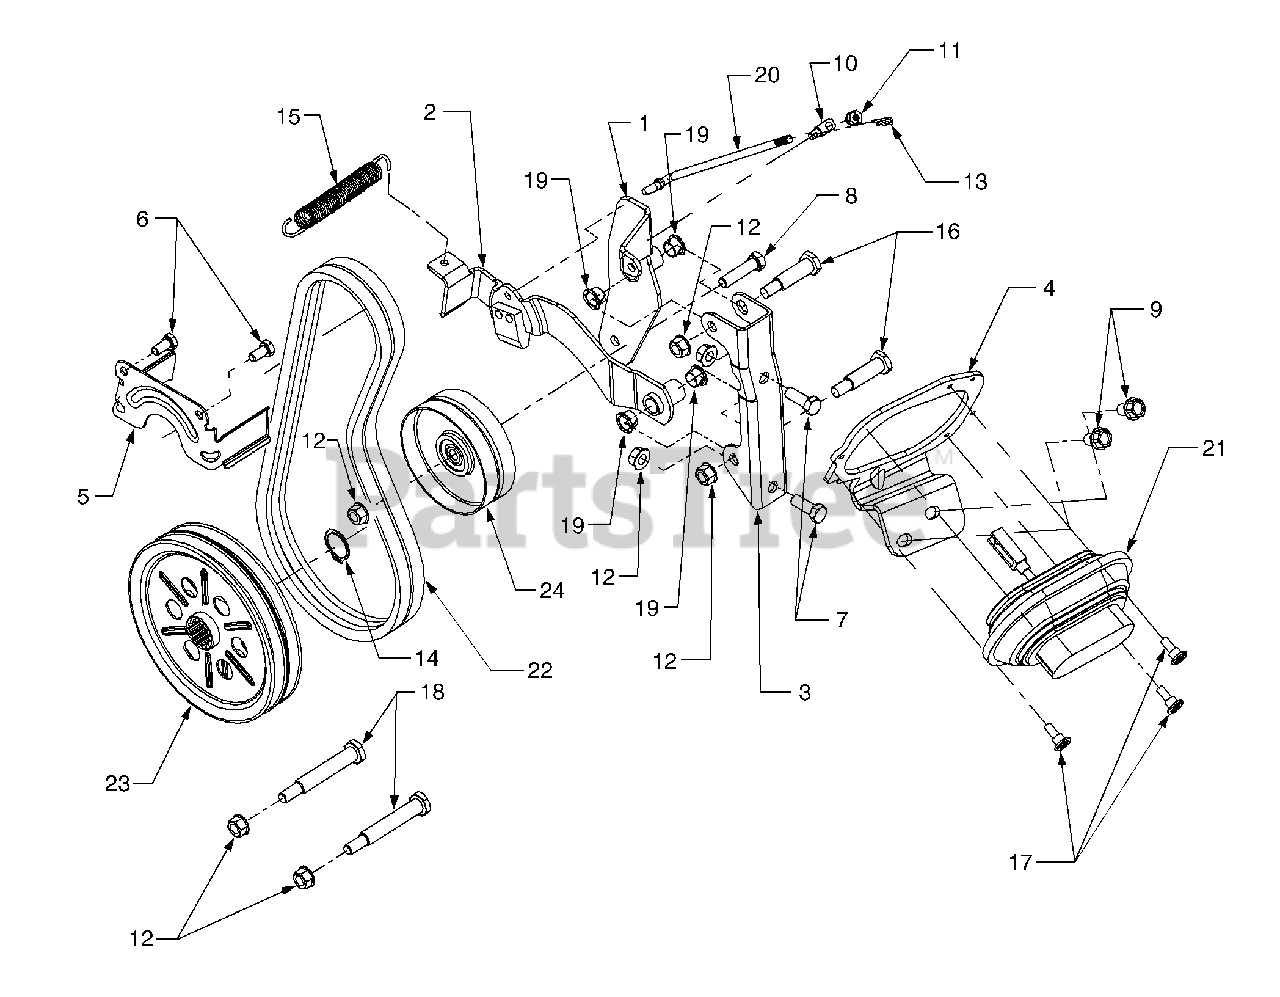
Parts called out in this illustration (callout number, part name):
1	Bracket, Idler
2	Bracket Assembly, Brake
3	Bracket, PTO Mounting
4	Bracket, Actuator
6	Screw, Hex Cap 5/16-24 x .625 GR5
7	Screw, Hex Cap 3/8-16 x 1.0 GR5
8	Screw, Hex Cap 3/8-16 x 1.5 GR5
9	Screw, Hex Wash. Hd. Tapp 3/8-16 x .75
10	Ferrule, Brake Adjustment
11	Nut, Hex Insert Lock, 1/4-20
12	Nut, Flange Lock, 3/8-16
13	Pin, Internal Cotter
14	Snap Ring, 1.0 Dia Shaft
15	Spring, Extension, .530 x 4.74
16	Shoulder Screw, .498 x 1.45
17	Shoulder Screw, .375 x .28
18	Shoulder Screw
19	Bearing, Nylon Flange
20	Rod, PTO Brake
21	Vacuum Actuator
22	V-Belt, A-Section x 37.63 (Set of two belts)
23	Pulley, PTO Drive. 6.75-Double
24	Pulley, Flat Idler, 4.0
